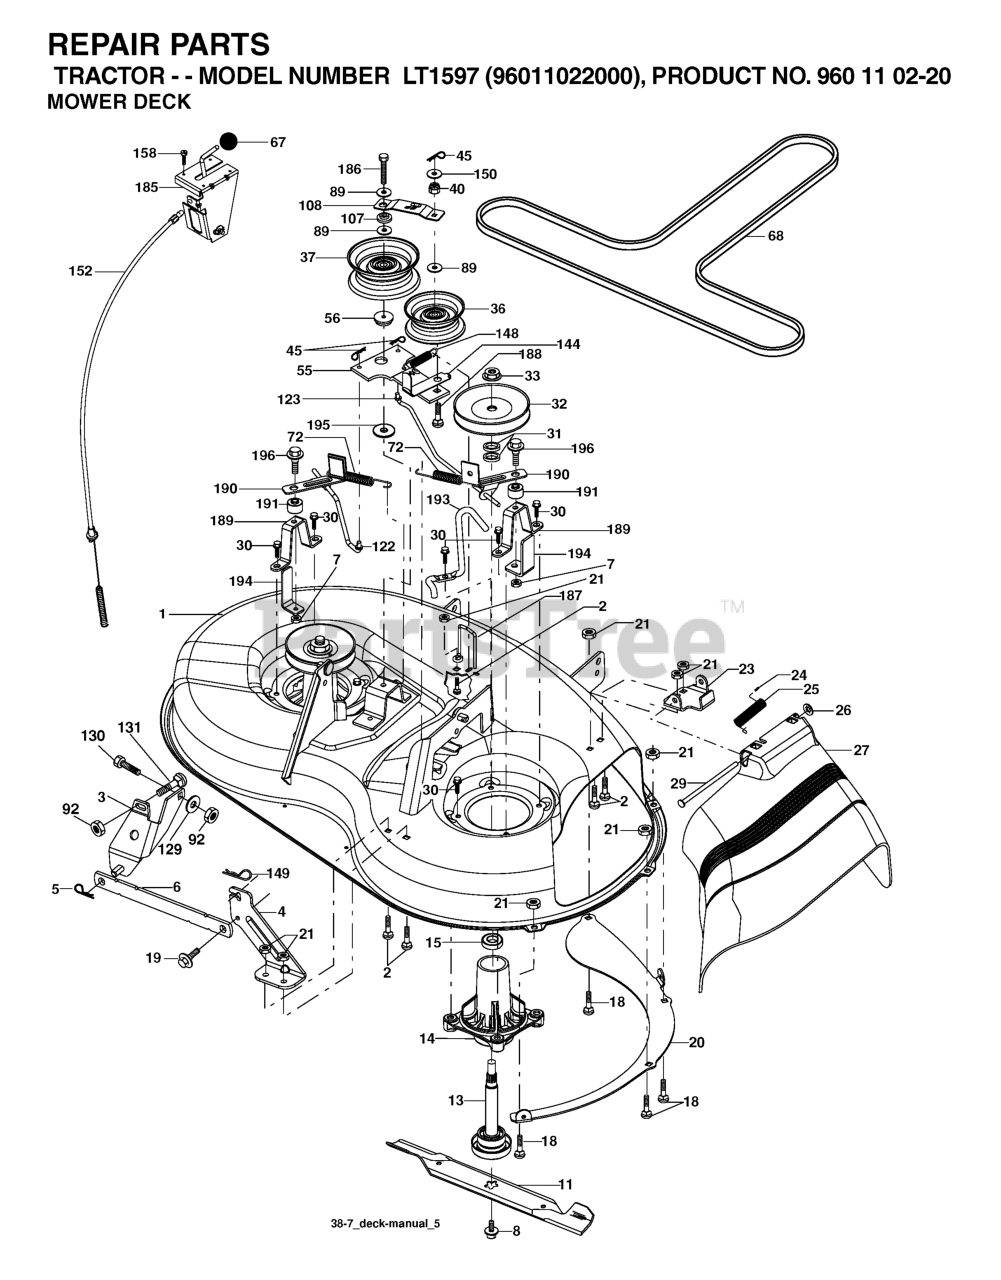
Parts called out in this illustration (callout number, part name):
1	DECK SVCX1 38/94 192556X431
2	RP BOLT 5/16-18 X3/4 ZN/YEL GR
3	BRKT ASM SWAY BAR
4	BRACKET DECK SWAY BAR 38"/42"
5	RETAINER-SPRNG RB
6	BAR SWAY DECK
7	NUT.71038.31-18.HEX.NYLOCK
8	BOLT.WASHER.ASM.7/16-2
11	BLADE 38" PREMIUM
13	SHAFT.ASM.MDRL.N/GREASE.38
14	RP.HOUSING.MANDREL.4PT.
18	BOLT
19	BOLT SHD 5/16-18
20	BAFFLE.VORTEX.FRONT.38"
21	LOCKNUT
23	BRKT.DEFLECTOR.38"2005+
24	CAP-SLEEVE LT
25	SPRING.TORSION.DEFLECT
26	NUT PUSH M
27	SHIELD.DEFLECTOR.MWR.38-7/97CM
29	ROD.HINGE
30	SCREW, WASHER HEAD
31	WASHER.SPACER.MANDREL
32	PULLEY MANDREL
33	NUT.FLANGE.LOCK.TOP
36	FLAT IDLER PULLEY
37	PULLEY.IDLER.FLAT.UNPLATED
45	RETAINER M
46	SCREW.1/4-20X5/8
56	SPACER.RETAINER.MOWER
67	KNOB T (3/8 HOLE)
68	V-BELT.MOWER.38"2005+
72	SPRING.BRAKE.RETURN.38"
89	WASHER
92	NUT
107	SPACER.IDLER.ARM
108	STIFFENER.IDLER.ARM
122	LINKAGE.BRAKE.LH.38"
123	LINKAGE.BRAKE.RH.38"
129	WASHER
131	BOLT D
144	KEEPER BELT
148	IDLER RETURN SPRING
149	SPRING.RETAINER.YELLOW.ZINC
152	CABLE.CLUTCH.38".SERVICE
158	SCREW
185	HEAD ASM. CABLE CLUTCH
186	SCREW.HXWSH.3/8
187	KEEPER BELT
188	BOLT, CARRIAGE IDLER
189	STAND, BRAKE
190	ARM, BRAKE
191	BRAKE.SPACER.38".DECK
192	BOLT/WASHER ASM 5/16-18
193	KEEPER BELT RH MANDREL
194	GUARD BRAKE
195	WASHER 12/32X2X10GA
